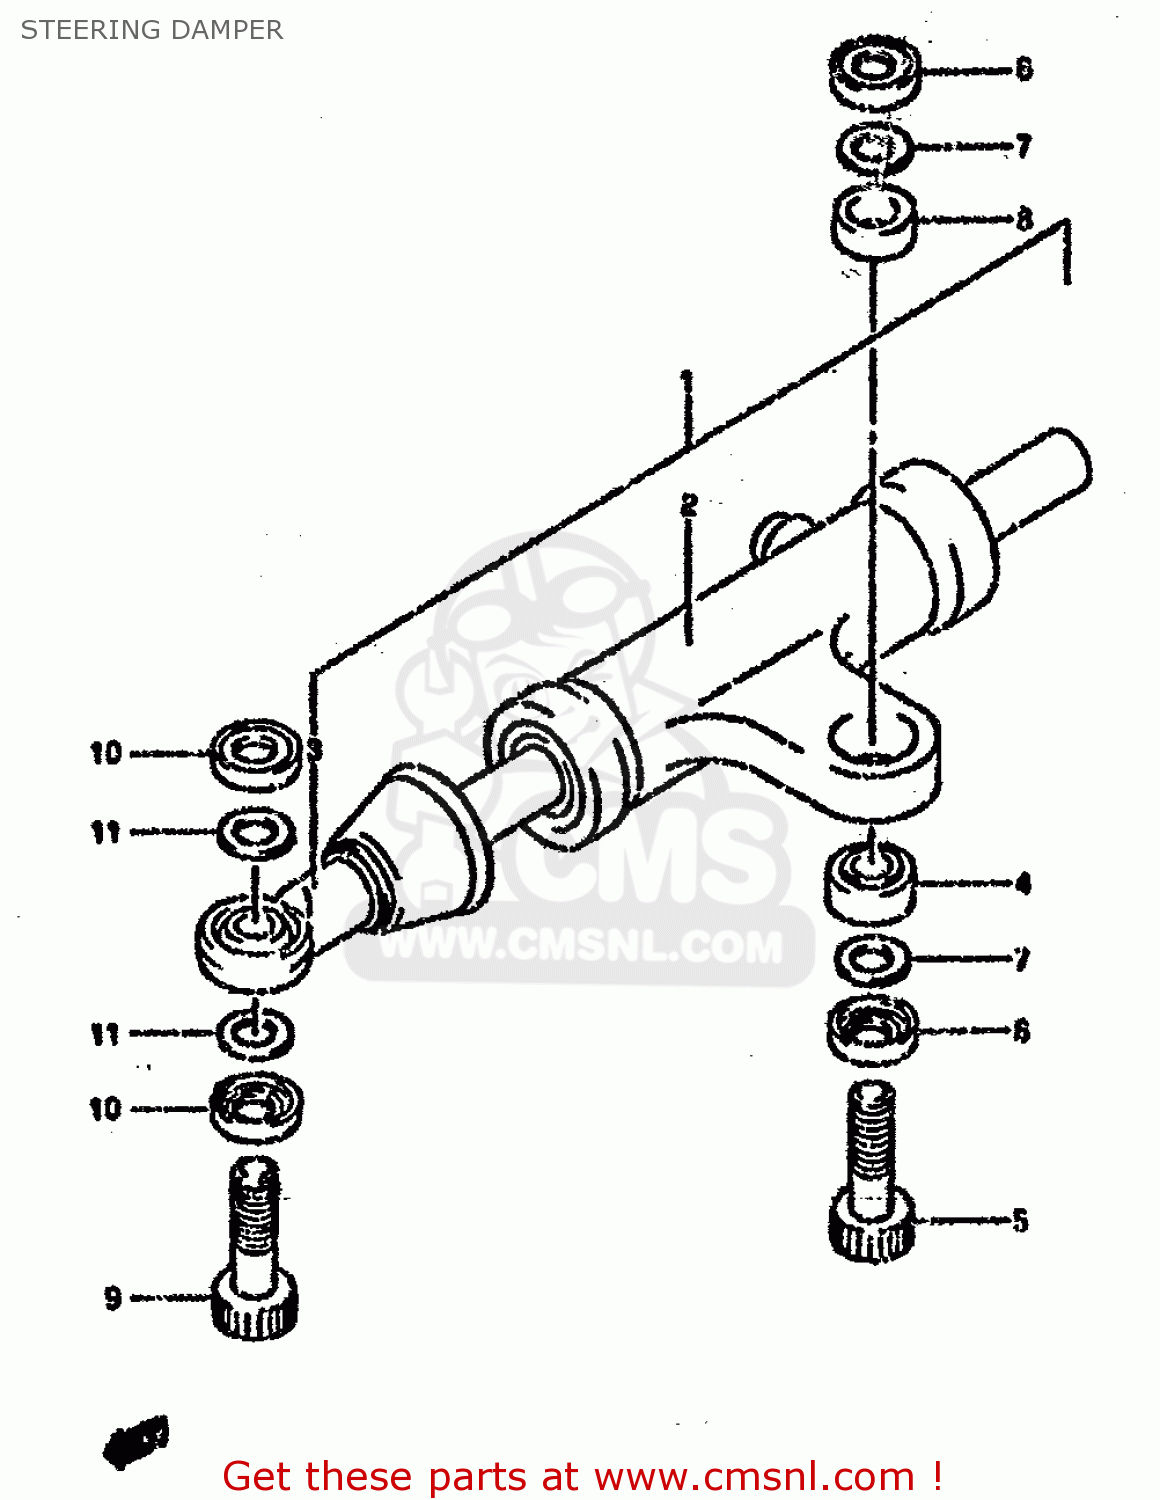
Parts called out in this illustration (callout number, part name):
1	DAMPER ASSEMBLY,STEERING
2	DAMPER,STEERING
3	PILLOW BALL,ROD END
4	BEARING(8X17.5X11)
5	BOLT
6	7
7	SHIM
8	SPACER (8.4X14X6)
9	BOLT
10	11
11	SHIM
